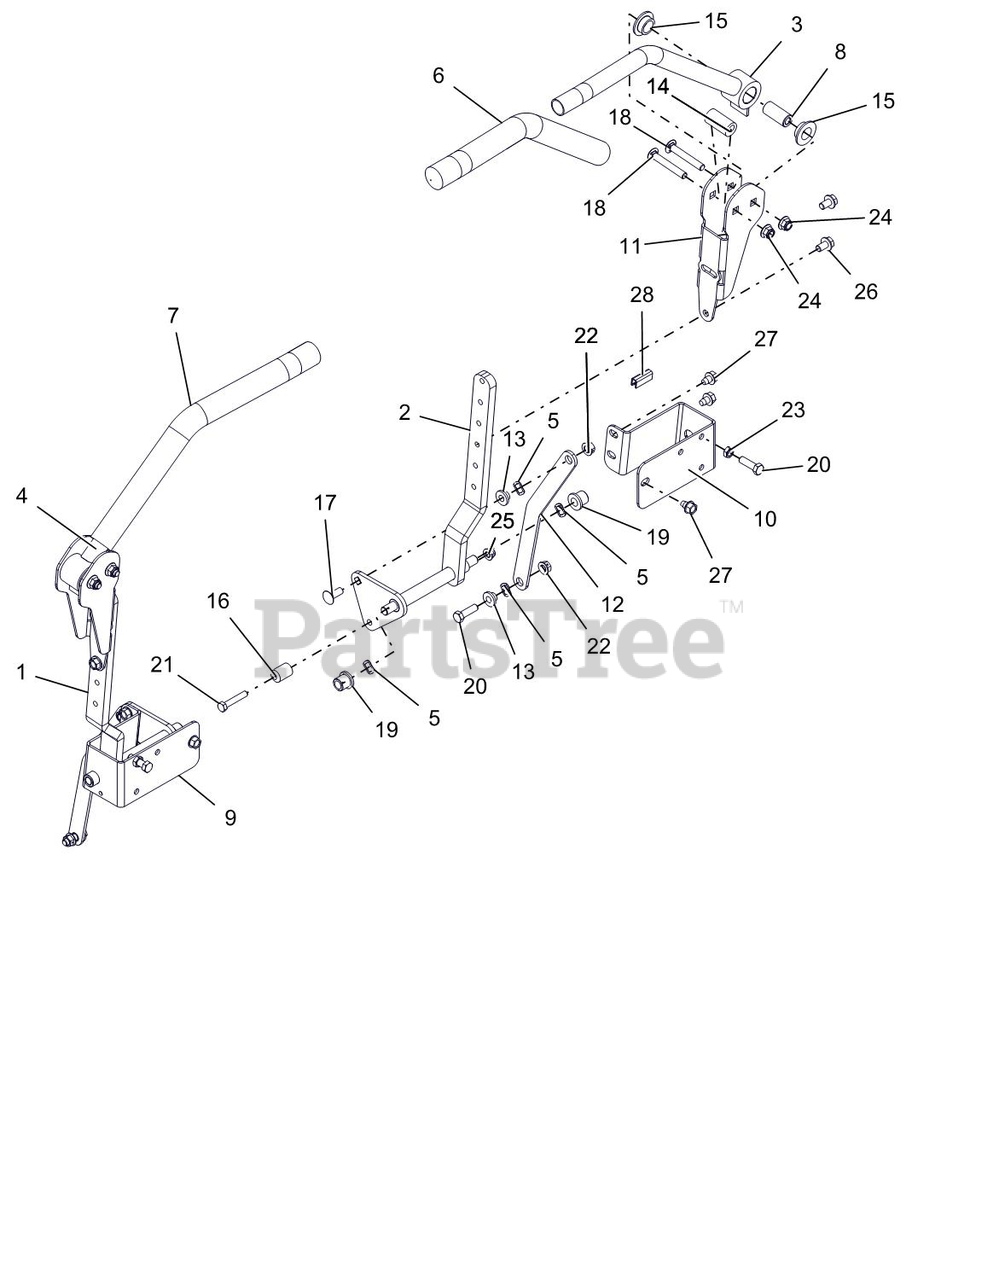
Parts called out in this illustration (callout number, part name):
1	WLDMT, RH LOWER CONTROL ARM (BLACK)
2	WLDMT, PT/PT100 LH LOWER CONTROL ARM (BLACK)
3	WLDMT, LH CONTROL HANDLE (BLACK)
4	WLDMT, RH CONTROL HANDLE (BLACK)
5	WAVE WASHER .531X.781X.125 FH
6	GRIP, HANDLEBAR
7	GRIP, HANDLEBAR
8	SPCR, STEERING ARM
9	STOP, RH PT/PT100 DRIVE CONTROL (RED)
10	STOP, LH PT/PT100 DRIVE CONTROL (RED)
11	BRKT, ADJ UPPER CONTROL ARM
12	LINK, DRIVE CONTROL(BLACK)
13	BSHG, FLG .385 X .500 X .875 X .406
14	BSHG, ECCENTRIC .328 X .750 X 1.625
15	BSHG, FLANGE .762 X 1.48 X .44 NYLON
16	ECCENTRIC
17	BOLT, CARRIAGE 0.375-16X1 GR5
18	BLT-RHDSSQNK .38-16X2.50 G5YZ
19	BHSG-FLG .500X.750X.750X.125
20	BOLT, HEX 0.375-16X1.25 GR5
21	BOLT, HEX 0.313-18X1.75 GR5
22	NUT, LK-CTR-FLG .38-16 YWZC
23	NUT, JAM .375-16 YWZC
24	NUT-LK-NYL-FLG .38-16 YWZC
25	NUT-LK-NYL-FLG .31-18 YWZC
26	BLT-SERHFWH .38-16X.62 YWZC
27	SCR-TAP .38-16X.50 HWH TR YWZ
28	STRIP, COWL - 1.25 LG
